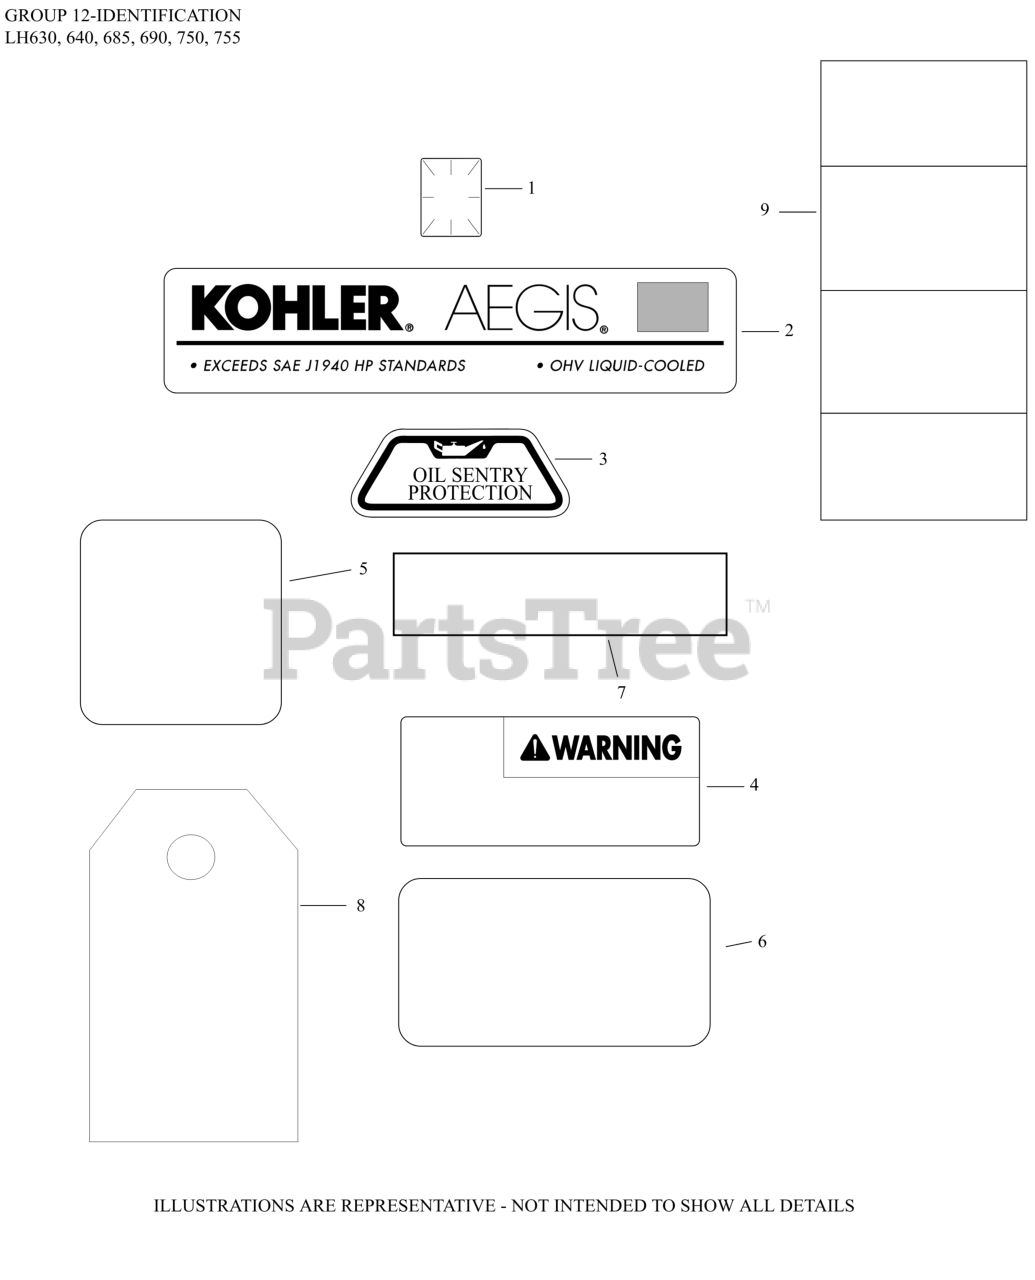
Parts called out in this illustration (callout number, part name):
1	DECAL, CLEAR LAMINATE-(#2511370S)
2	LABEL, 27HP (LH750) - DISC.
3	DECAL, OIL SENTRY - DISCONTINUED
4	DECAL, ROTATING FAN WARNING-DISC.
8	TAG, HANG (NO COOLANT)
9	DECAL, HIGH ALTITUDE
